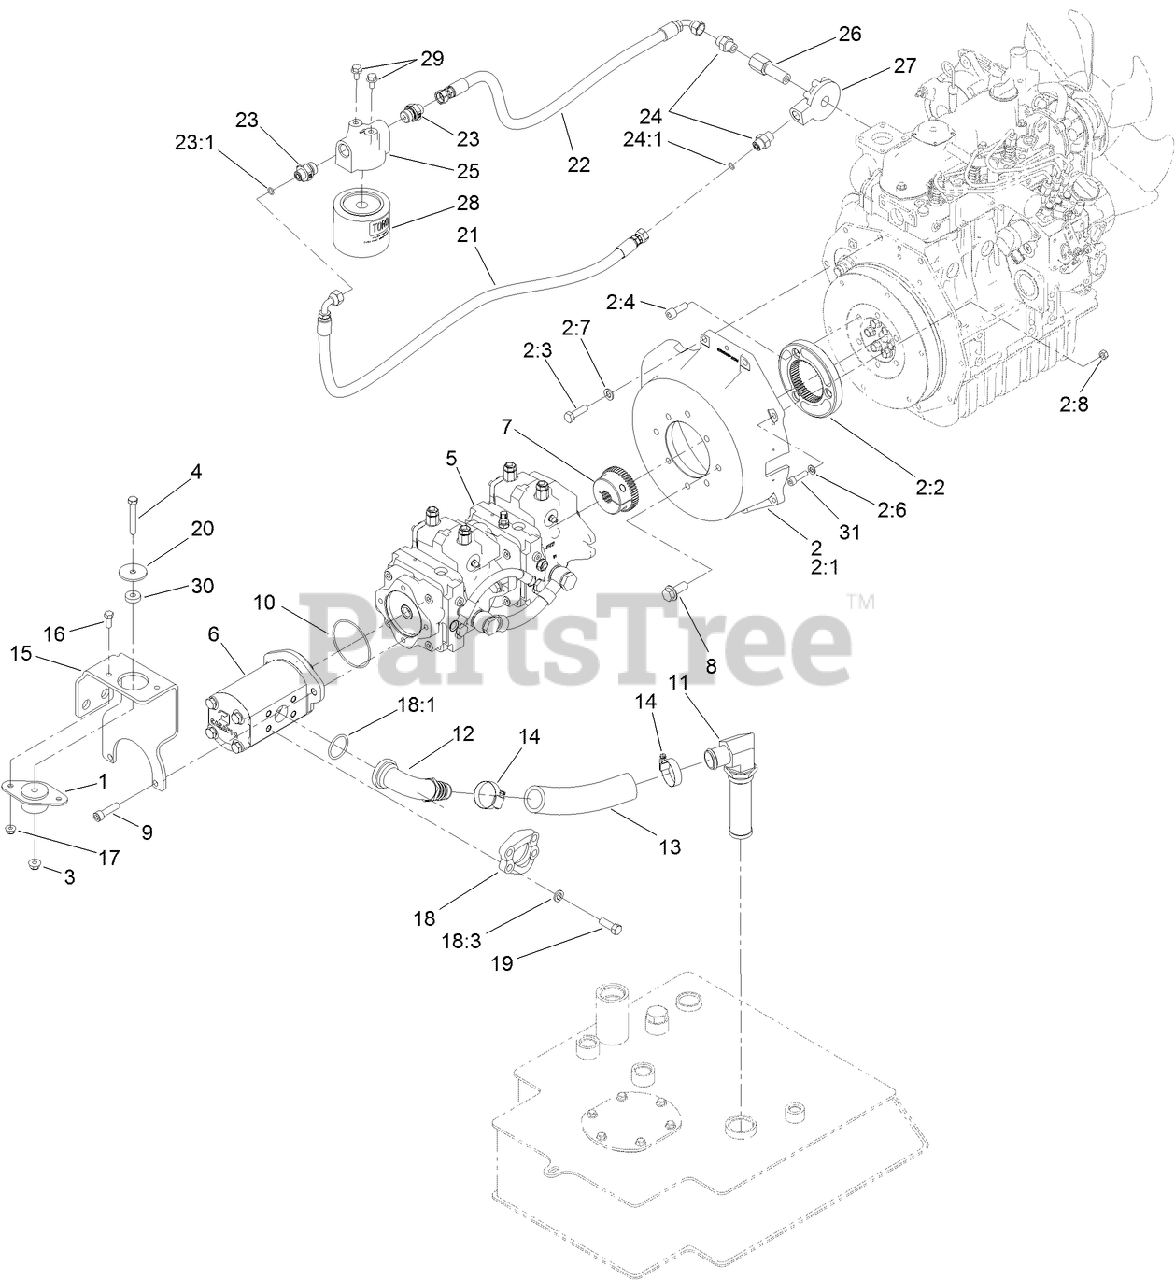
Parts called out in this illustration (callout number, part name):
1	MOUNT-ENGINE
2	MOUNT-PUMP
2:1	HOUSING-PUMP MOUNT
2:2	FLANGE-COUPLER
2:3	SCREW-HH
2:4	SCREW-HSH
2:5	SCREW-HSH
2:6	WASHER-PLAIN
2:7	WASHER-FLAT
2:8	NUT-HEX
3	NUT-HF, NI
4	SCREW-HH
5	PUMP-TANDEM
6	PUMP-GEAR
7	HUB-PUMP
8	SCREW-HHF
9	SCREW-SH
10	O-RING
11	STRAINER-SUCTION
12	FITTING
13	HOSE-SUCTION
15	PLATE-SUPPORT, PUMP
16	SCREW-HH
17	NUT-HF, NI
18	FLANGE KIT
18:1	O-RING
18:2	SCREW-HH
18:3	WASHER-LOCK
19	SCREW-HH
20	WASHER-REBOUND
21	HOSE-HYD
22	HOSE-HYD
23	FITTING-HYD
23:1	O-RING
24	FITTING-HYD
24:1	O-RING
25	BASE-FILTER
26	PIPE-JOINT
27	BASE-FILTER
28	FILTER-OIL
29	SCREW-HHF
30	SPACER
31	SCREW-HSH
